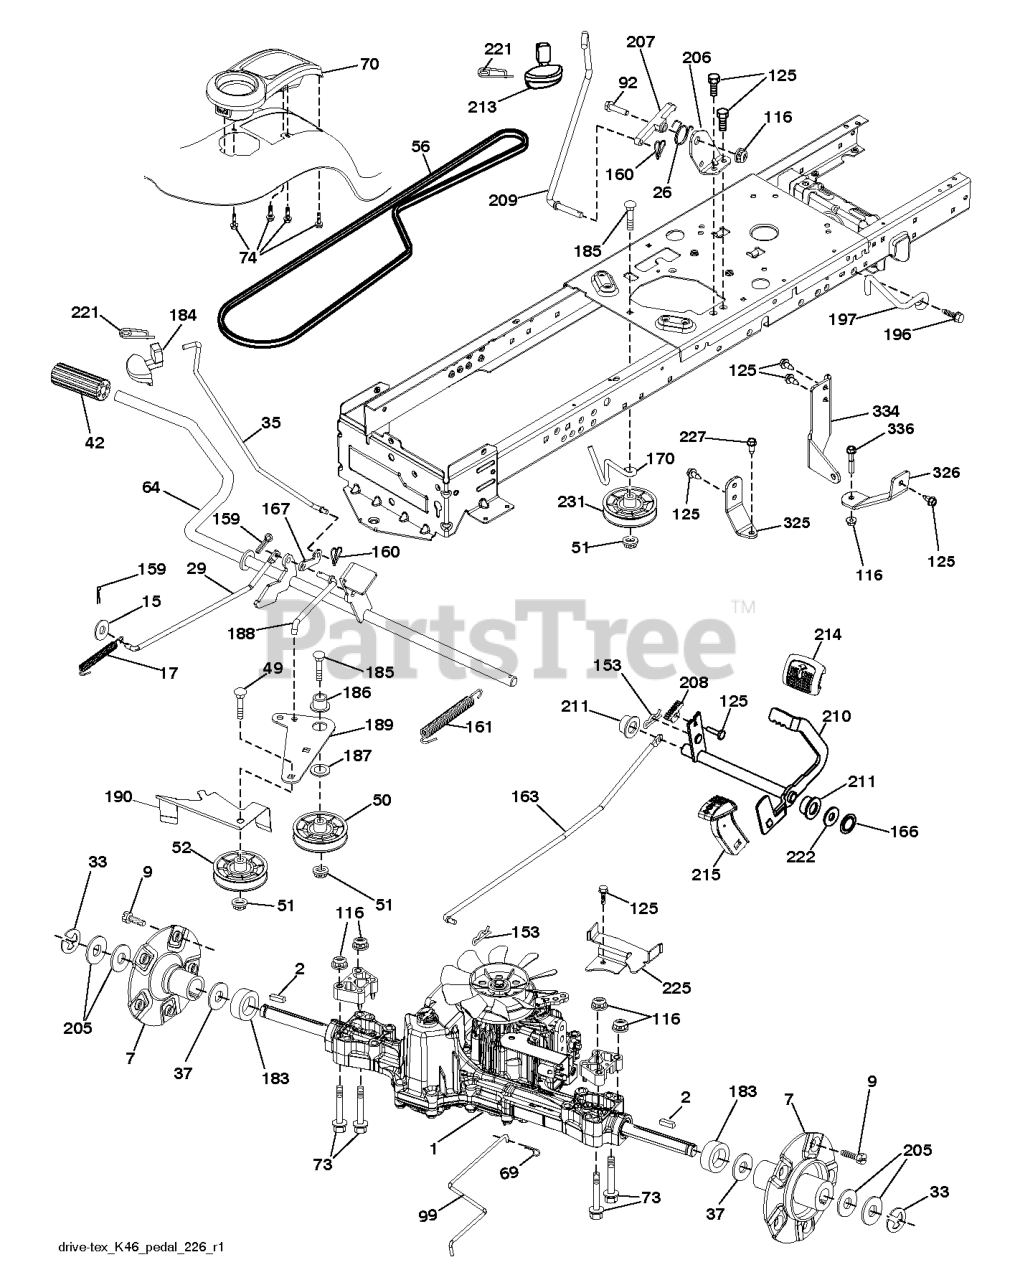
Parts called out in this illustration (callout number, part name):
2	KEY.SQUARE.187X2.500
7	HUB.ASM.WHEEL.REAR.22"
9	HUB BOLT
17	SPRING.BRAKE.K46.GREEN
26	SPRING.RETURN.CRUISE
29	ROD.BRAKE.K46
33	E-RING LT
35	ROD ROD.PARKINGBRAKE.GT.HUSQ/P
37	WASHER.HARDENED
42	PEDAL COVER
49	BOLT
50	IDLER.FLAT.910.OFFSET
51	NUT LOCK FLG 3/8-16 UNC
52	IDLER.V-GROOVE.910.OFFSET
64	SHAFT.ASM.PEDAL.BRK.CNTR
69	HAIRPIN.SOFT.ZINC.059X1.125
70	CONSOLE.TOOLBOX.PCH.ERGO.BLACK
74	SCREW.HI-LO.CONSOLE
92	BOLT
99	ARM.PIVOTING.TCRD.GEN2.5.BAGGE
116	NUT LOCK HEX FLANGE 5/16-18
125	SCREW
153	RETAINER M
159	COTTER PIN
160	RETAINER CLIP
161	SPRING, RETURN LT
163	ROD.CONTROL.K57R.K46
166	NUT.PUSH.625
167	LATCH.BRAKE.SPRING
170	KEEPER.CENTER SPAN.1.688
183	SPACER.SPLIT.800X.350
184	HANDLE.PARKING.BRAKE.H (BLK)
186	SPACER.RETAINER
187	WASHER 12/32X2X10GA
188	LINK.CLUTCH.GROUND DRIVE.LONG
189	BELLCRANK.GROUND.DRIVE.TEX.
190	KEEPER.BELLCRANK.DRIVE
196	SCREW 3/8-16X1
197	BRKT.42.FCS.CLUTCH.ANTIROTATIO
206	BRACKET.MOUNT.CRUISE.LATCH
207	LATCH.CONTROL.CRUISE.TEX
208	GEAR.SECTOR.CONTROL.CR
209	ROD ROD.CRUISECONTROL.GT.HUSQ/
210	ROCKER.ASM.PEDAL.CONTR
211	BEARING.NYLON
213	KNOB.CONTROL.CRUSIE.HU
214	PEDAL.FORWARD.PAD.TEX
215	PEDAL.COVER.REVERSE.CRD.X428BK
221	RETAINER.SPRING.CLIP.H
222	WASHER 21/32 X 1-1/4 X 10 GA.
225	KEEPER.BELT.TRANSAXLE.K46
227	SCREW
231	IDLER.V-GROOVE.1.688.OFFSET
325	BRACKET.TRQ.STP.46.20".TIRE.LH
326	BRCKT.PNT.TRQ.STP.46.20TIRE.RH
334	SWAY.ROD.BRACKET.K46.X431
336	BOLT.5/16-18X1-3/4.FLANGED.HEX
